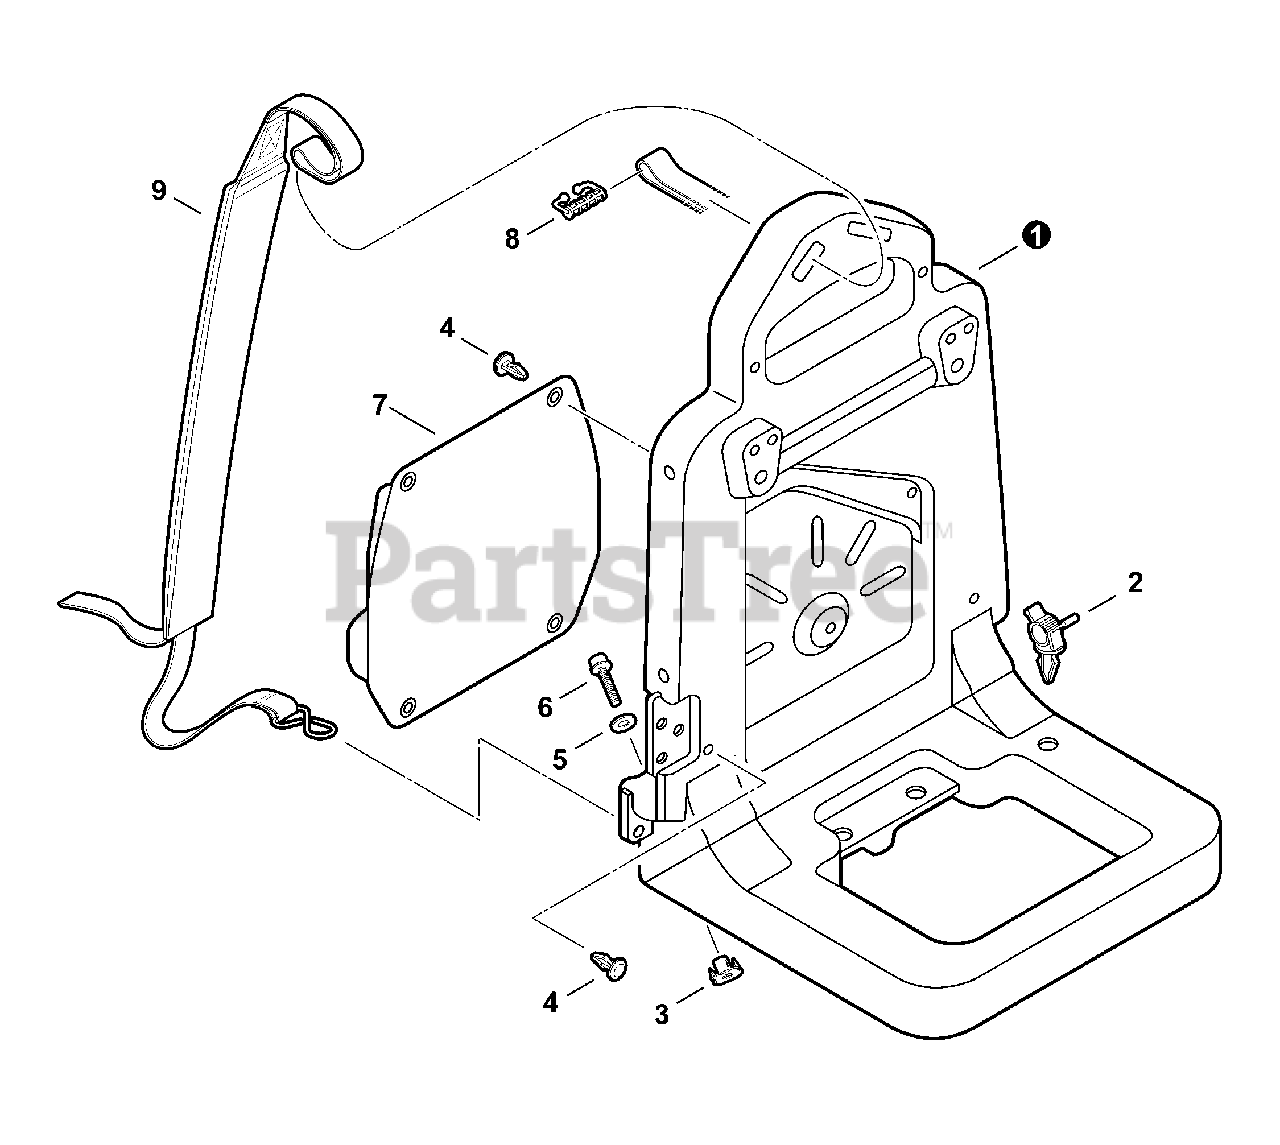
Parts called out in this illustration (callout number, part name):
1	FRAME, BACKPACK
2	CLIP, CABLE
5	WASHER - 6
6	SCREW - 6×25
7	CUSHION, BACKPACK
8	RETAINER, HARNESS
9	BACKPACK STRAP ASSY
